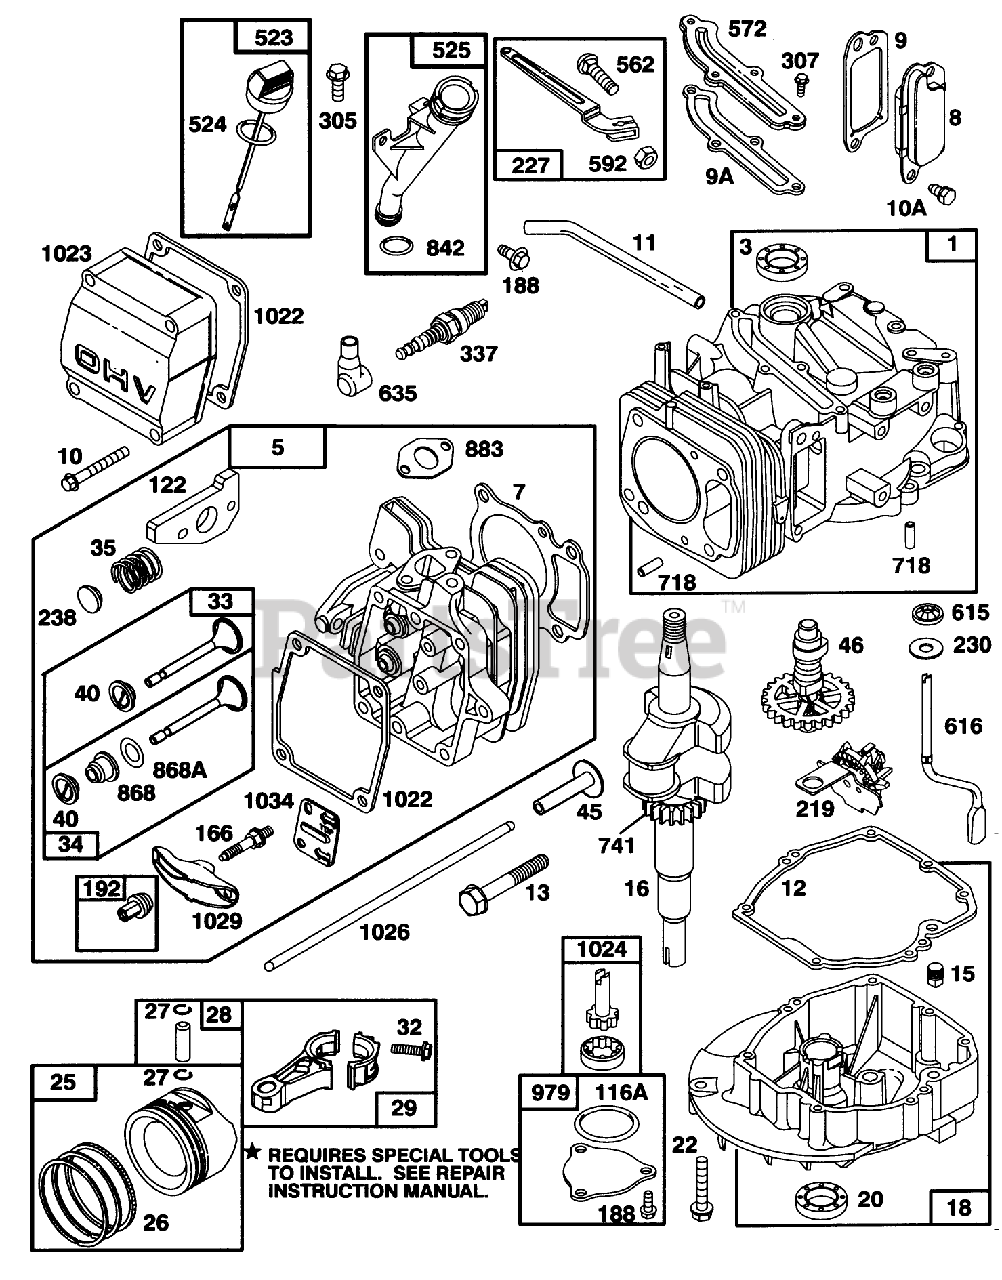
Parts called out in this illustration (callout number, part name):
3	SEAL - OIL
7	CYLINDER HEAD GASKET
9	BREATHER GASKET
9A	GASKET-BREATHER
12	ENGINE BASE GASKET
20	SEAL-OIL
104	FLOAT HINGE PIN
116	SEALING GASKET
116A	O RING SEAL
118	VALVE KIT - NEEDLE
121	CARBURATOR OVERHAUL KIT
122	ADAPTER ASSEMBLY
127	PLUG
134	VALVE-FLOAT
137	FLOAT BOWL GASKET
163	AIR CLEANER GASKET
358	GASKET SET
524	O-RING
634	SEAL WASHER
842	O-RING
868	SealAssy-Valve
868A	Seal-Valve
883	EXHAUST GASKET
977	CARBURATOR GASKET SET
1022	ROCKER COVER GASKET
1039	FLOAT LIMITER
1041	SEAL - FOAM
